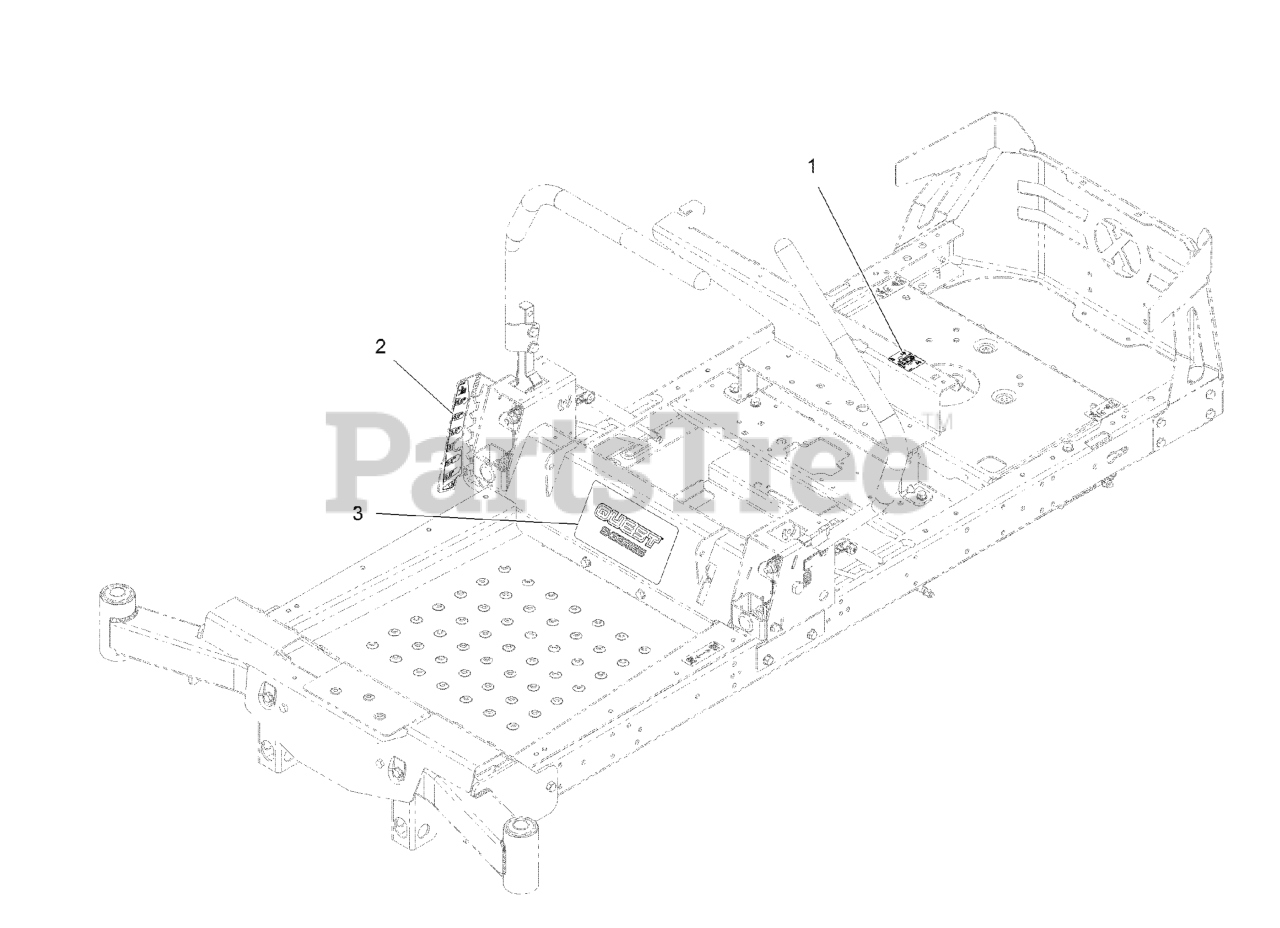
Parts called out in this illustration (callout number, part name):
1	DECAL-SERVICE, CE
2	DECAL-HOC
3	DECAL, QUEST S SERIES
